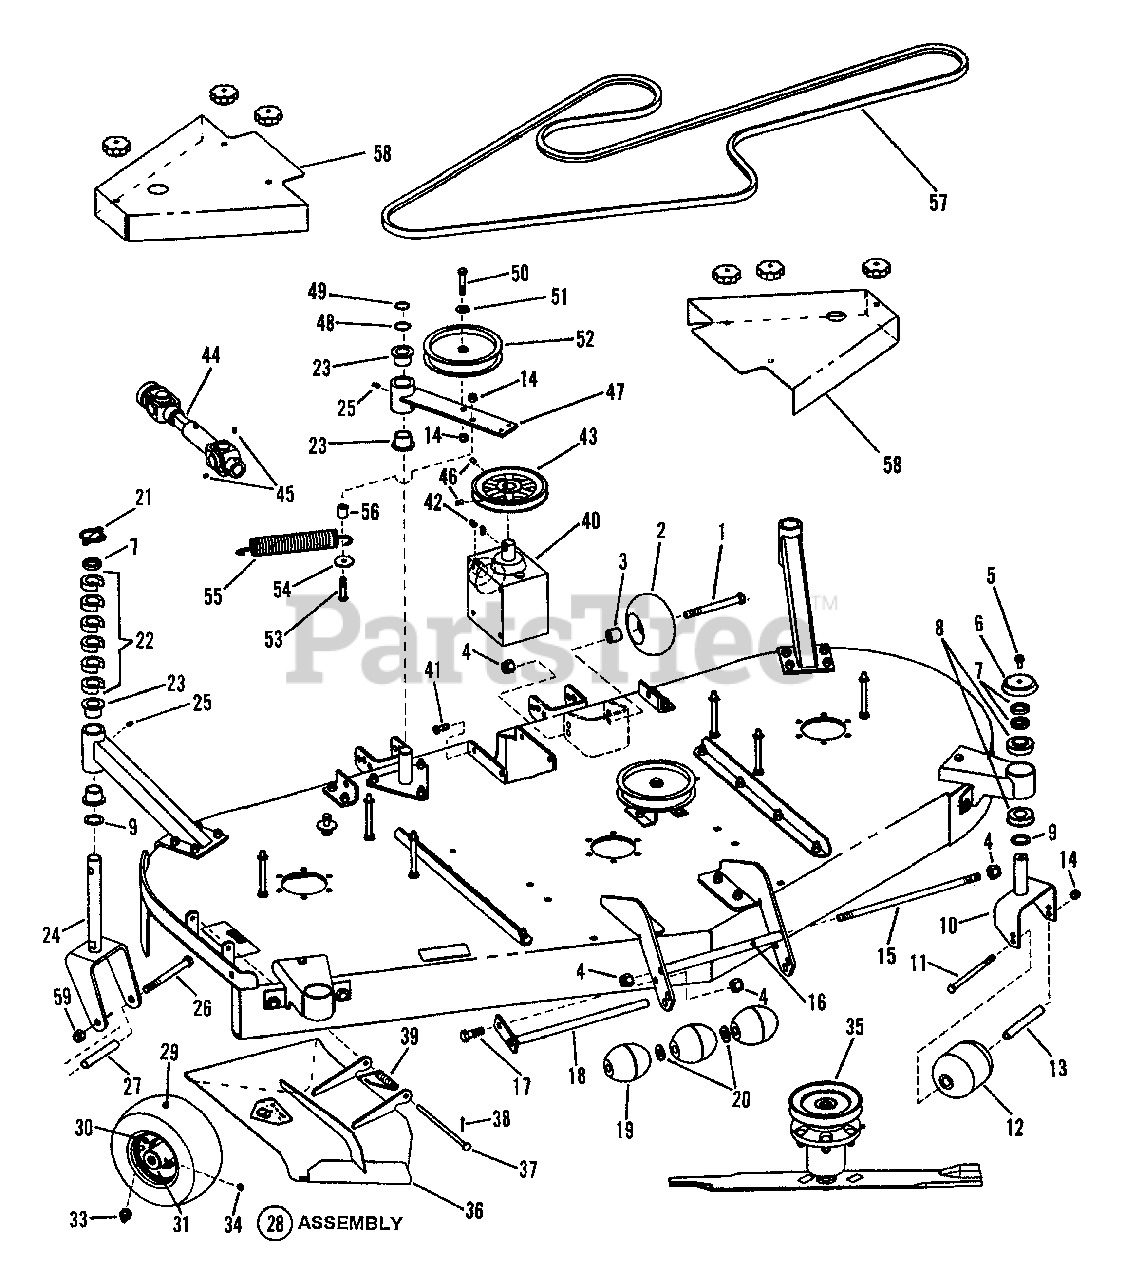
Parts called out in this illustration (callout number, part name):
1	BOLT, 1/2-13 X 5 GD5 YZ
2	GAGE WHEEL
3	SPACER, Gage Wheel
4	NUT, 1/2-1 3 Hex Nyloc
5	SCREW, 5/16-18 x 3/4" Hex Washer Self-Tap
6	CAP, Caster Shaft
7	SPACER, 1" x 1 3/8 x .30" (PM)
8	BEARING, Flanged Radial 1 x 2 x 23/32" Double Seal
9	BUSHING, Machine 1" I.D.
10	WELDMENT, Gauge Wheel Caster
11	BOLT, 3/8-16 X 6" GD5 CZ
12	ROLLER, 3-3/4 x 4-13/16" Nylon
13	TUBE, Axle
14	NUT, 3/8-16 HEX NYLON LOCK
15	ROD, 1/2-13 Threaded Roller
16	TUBE, Roller
17	BOLT, 1/2-13 X 1-1/2 GD5 CZ
18	WELDMENT, Pivot Pin
19	ROLLER, Low Density Polyethylene
20	WASHER, 5/8" SAE Flat
21	PIN, 7/16" Lynch
22	SPACER, Caster
23	BUSHING, Caster
24	WELDMENT, Caster Yoke
25	FITTING, 1/4-28, Straight, Grease
26	BOLT, 1/2-13 X 5-1/2" GD5 YZ
27	SLEEVE, Axle
28	ASSEMBLY, Wheel/Tire
29	TIRE, 9 x 3.50-4, 4 Ply Smooth
30	RIM, One Piece Steel, White
31	BEARING, Flanged
33	VALVE, Air
34	FITTING, 1/4-28, 45 Degree, Grease
35	GROUP, Spindle
36	WELDMENT, Chute Deflector ANSI Compliant
37	HINGE PIN, Chute
38	PIN, 3/32 x 1" Cotter
39	SPRING, Chute
40	GEARBOX, Right Angle 1.5:1
41	BOLT, 3/8-16 X 1" GD5 CZ
42	KEY, 1/4 x 7/8" Woodruff
43	PULLEY, Cast 6.50" O.D.
44	DRIVESHAFT, Telescoping
45	SCREW, 3/8-16 x 3/8" Set
46	SCREW, 5/16-18 x 5/8" Socket Head Set
47	WELDMENT, Idler Arm
48	WASHER, 1-1/32 I.D. x 1-1/4" O.D. Flat
49	E-RING, 1"
50	BOLT, 3/8-16 X 2, GD5, CZ
51	WASHER, 3/8" USS
52	PULLEY, 5-1/2" O.D. Idler
53	SCREW, 3/8-16 x 1-3/4" Hex Head Cap, Grade 5
54	WASHER, 13/32 I.D. x 1-1/2" O.D. Flat
55	SPRING, Extension
56	SPACER, 1/2 I.D. x 3/4" O.D. x .83
57	BELT, 153.12" HB Section
58	GUARD, Pulley
59	NUT, 1/2-13 HEX NYLON LOCK
